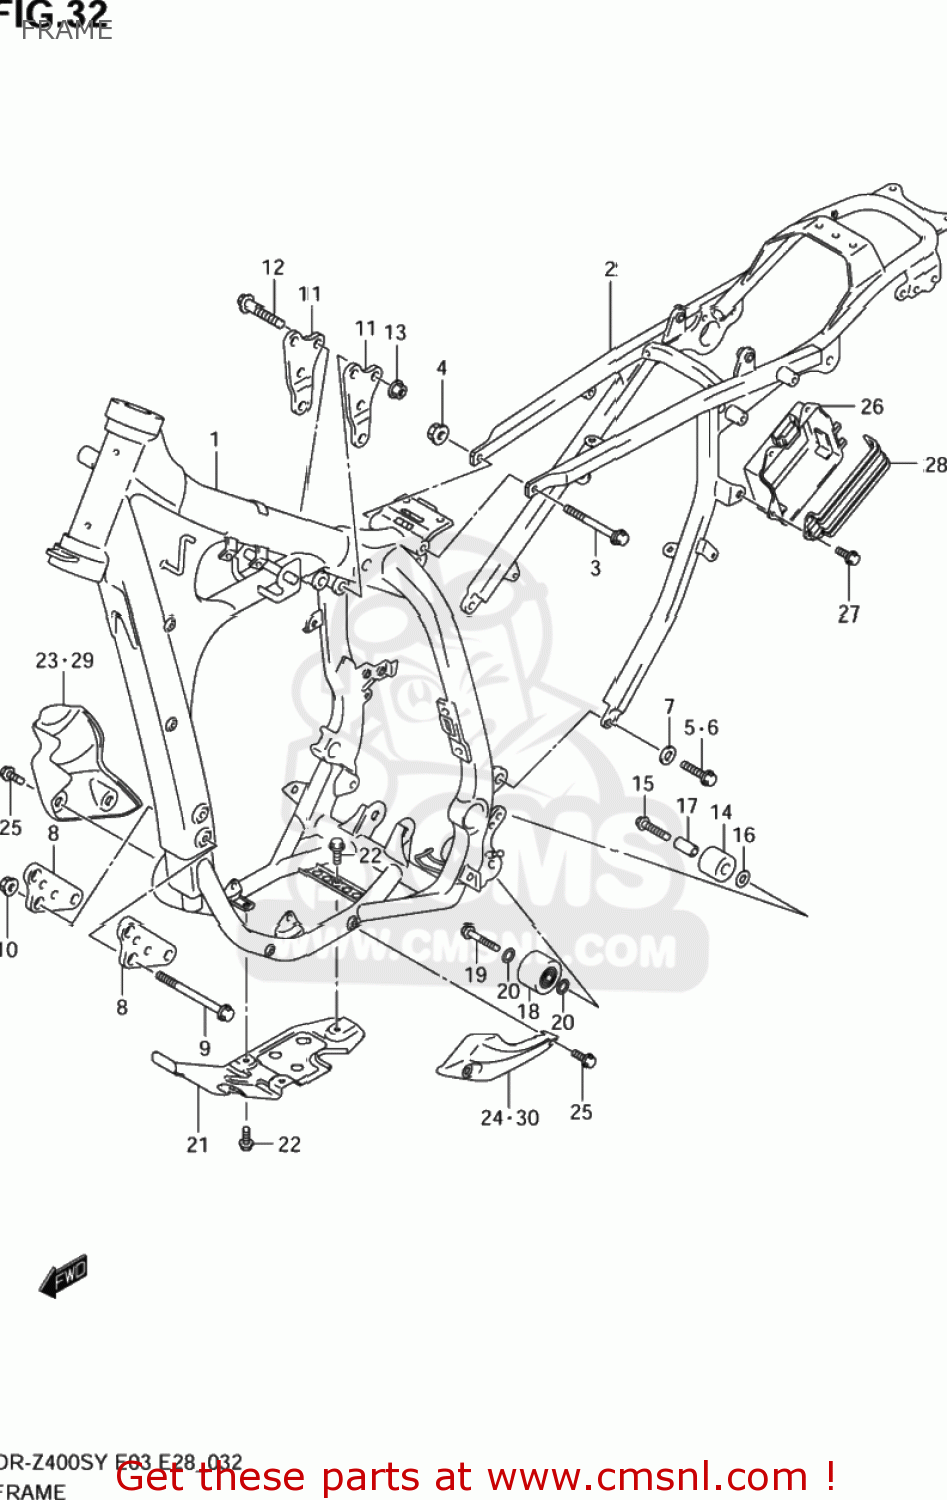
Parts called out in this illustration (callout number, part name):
1	FRAME(GRAY)
2	RAIL COMP,SEAT
3	BOLT(8X115)
4	NUT
5	BOLT(8X18)
6	BOLT(8X20)
7	WASHER(8.5X18X2)
8	PLATE,ENG MTG FR
9	BOLT(8X90)
10	NUT
11	PLATE,HEAD MTG RR
12	BOLT(8X50)
13	NUT
14	ROLLER,CHAIN CONTROL UPR
15	BOLT(8X41)
16	WASHER
17	SPACER(8.6X12.2X26.5)
18	ROLLER,CHAIN
19	BOLT(8X41)
20	SHIM(8X12X1)
21	PROTECTOR,ENGINE
22	BOLT
23	GUARD,WATER PUMP
24	GUARD,MAG COVER
25	BOLT(8X16.5)
26	HOLDER,BATTERY
27	BOLT(6X17.8)
28	BAND,BATTERY HOLDER
29	GUARD,WATER PUMP
30	GUARD,MAG COVER
